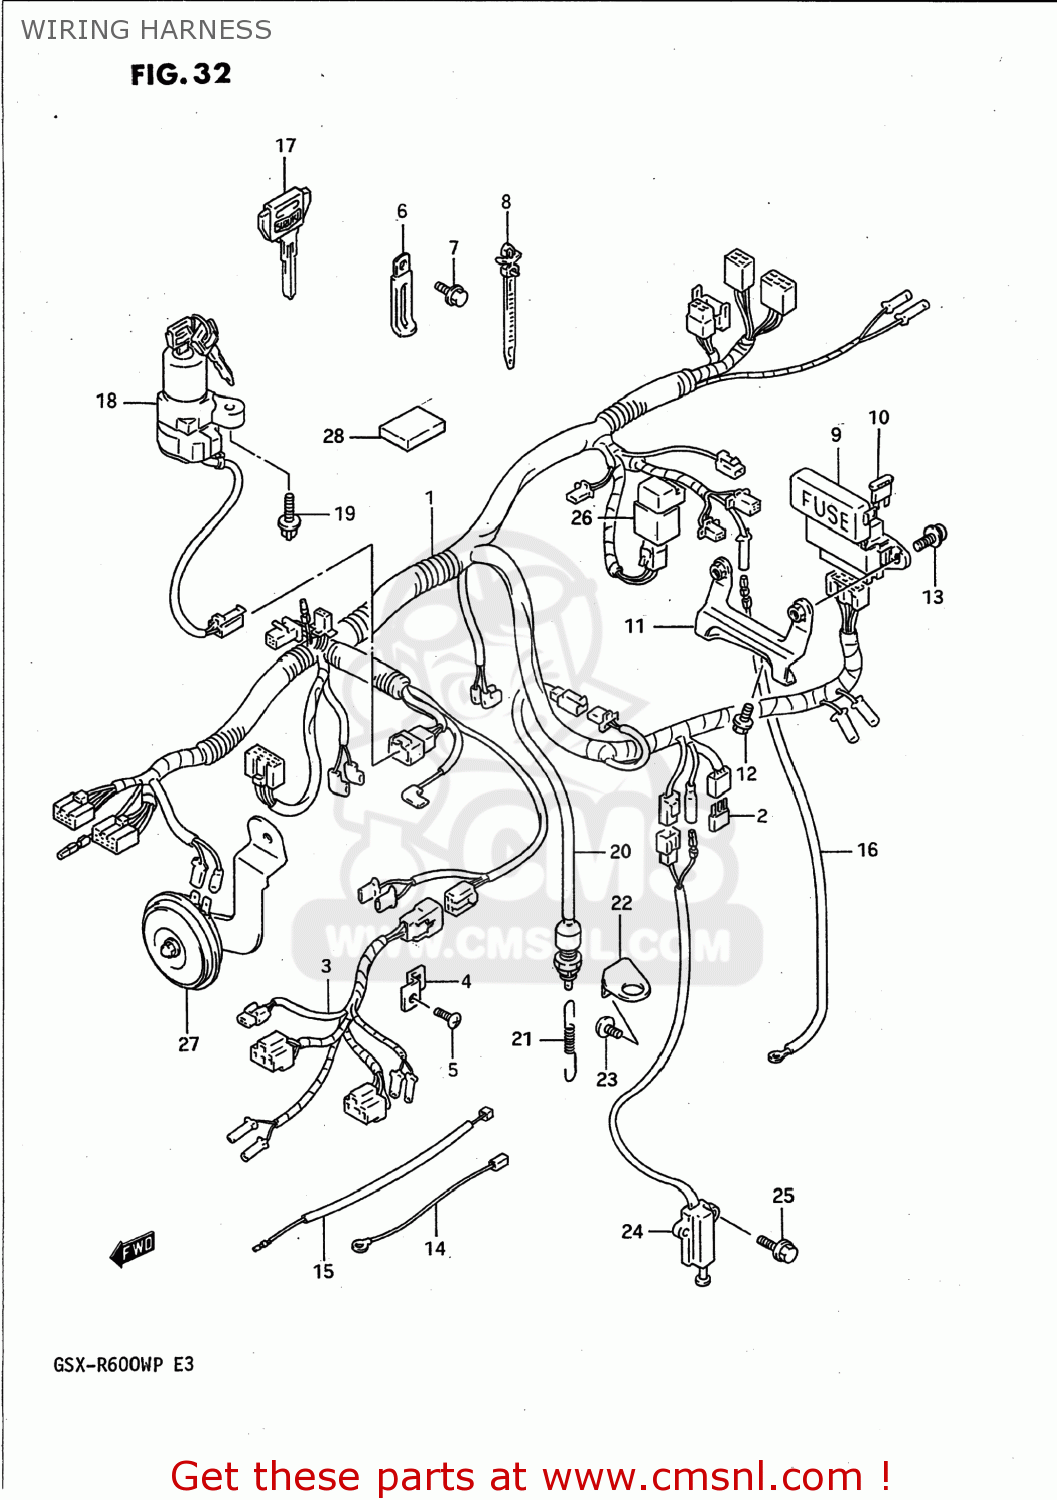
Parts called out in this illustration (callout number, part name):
1	HARNESS,WIRING NO.1
2	DIODE(STANLEY DE8804)
3	HARNESS,WIRING NO.2
4	HOLDER,COUPLER
5	SCREW
6	CLAMP
7	BOLT
8	CLAMP(L:90)
9	BOX ASSY,FUSE
10	FUSE(10A)
11	BRACKET,FUSE BOX
12	BOLT
13	VIS
14	WIRE,LEAD
15	WIRE,WATER TEMP GAUGE LEAD
16	WIRE
17	KEY,BLANK
18	LOCK ASSEMBLY,STEERING
19	SCREW(6X18)
20	SWITCH ASSY,STOP LAMP
21	SPRING
22	BRACKET,STOP LAMP SWITCH
23	SCREW(6X12)
24	SWITCH ASSEMBLY,SIDE STAND
25	BOLT 6X20
26	RELAY ASSEMBLY
27	HORN ASSEMBLY,LOW PITCH
28	TAPE
